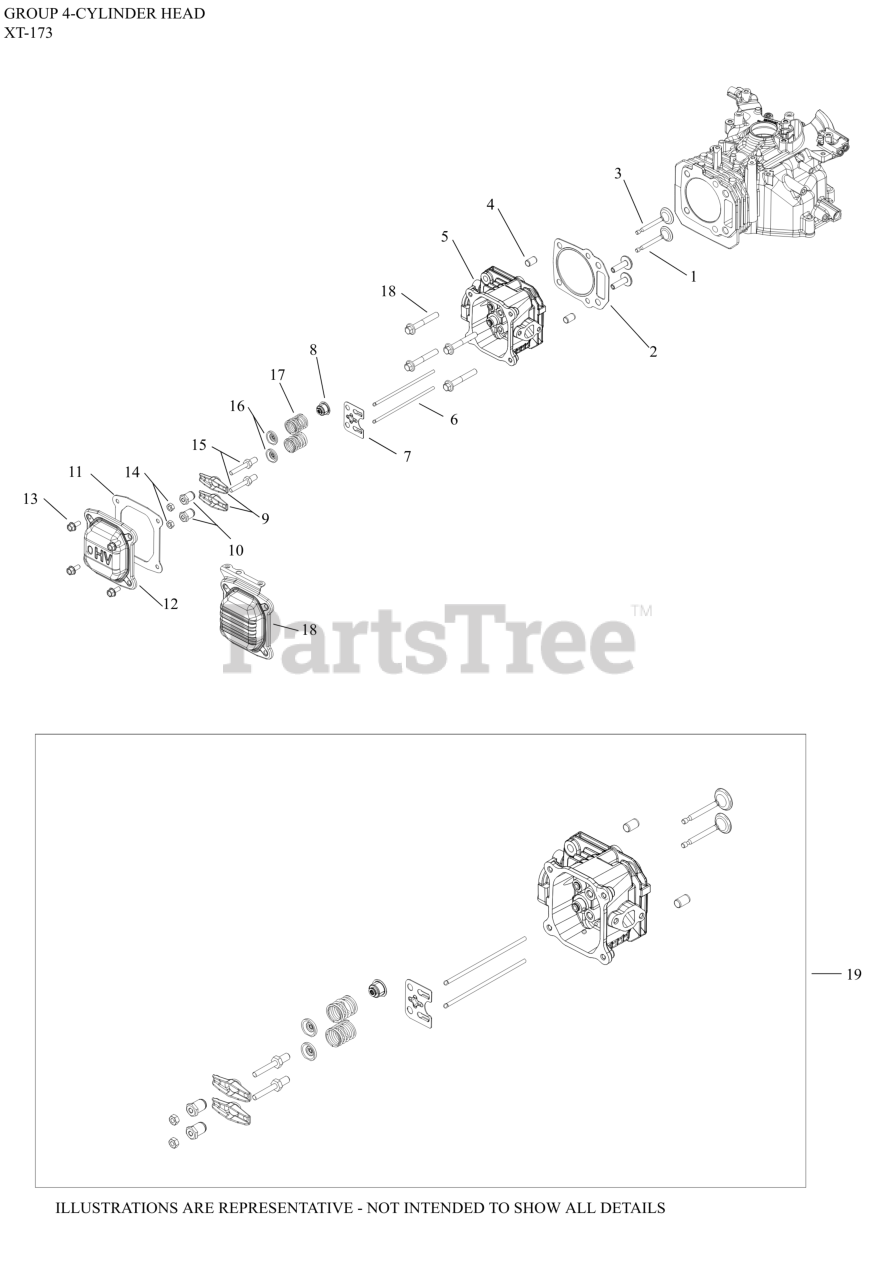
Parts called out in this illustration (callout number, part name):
1	VALVE, EXHAUST
2	KIT, HEAD GASKET-USE 14 841 34-S (XT)
3	VALVE, INTAKE
4	DOWEL, CYLINDER HEAD-(#1438013S)
5	KIT, CYLINDER HEAD
6	ROD, PUSH
7	PLATE, PUSHROD GUIDE
8	SEAL, VALVE STEM
9	ARM, ROCKER
10	PIVOT, ROCKER ARM
11	GASKET, VALVE COVER
14	NUT, HEX JAM
15	STUD, ROCKER ARM-USE 14 072 22-S
16	RETAINER, VALVE SPRING
17	SPRING, VALVE
18	SCREW, HEX FLANGE M8
NI	KIT, VALVE COVER - (#14 096 62-S)
NI	LIFTER, VALVE
NI	KIT, HEAD GASKET (CV173)
